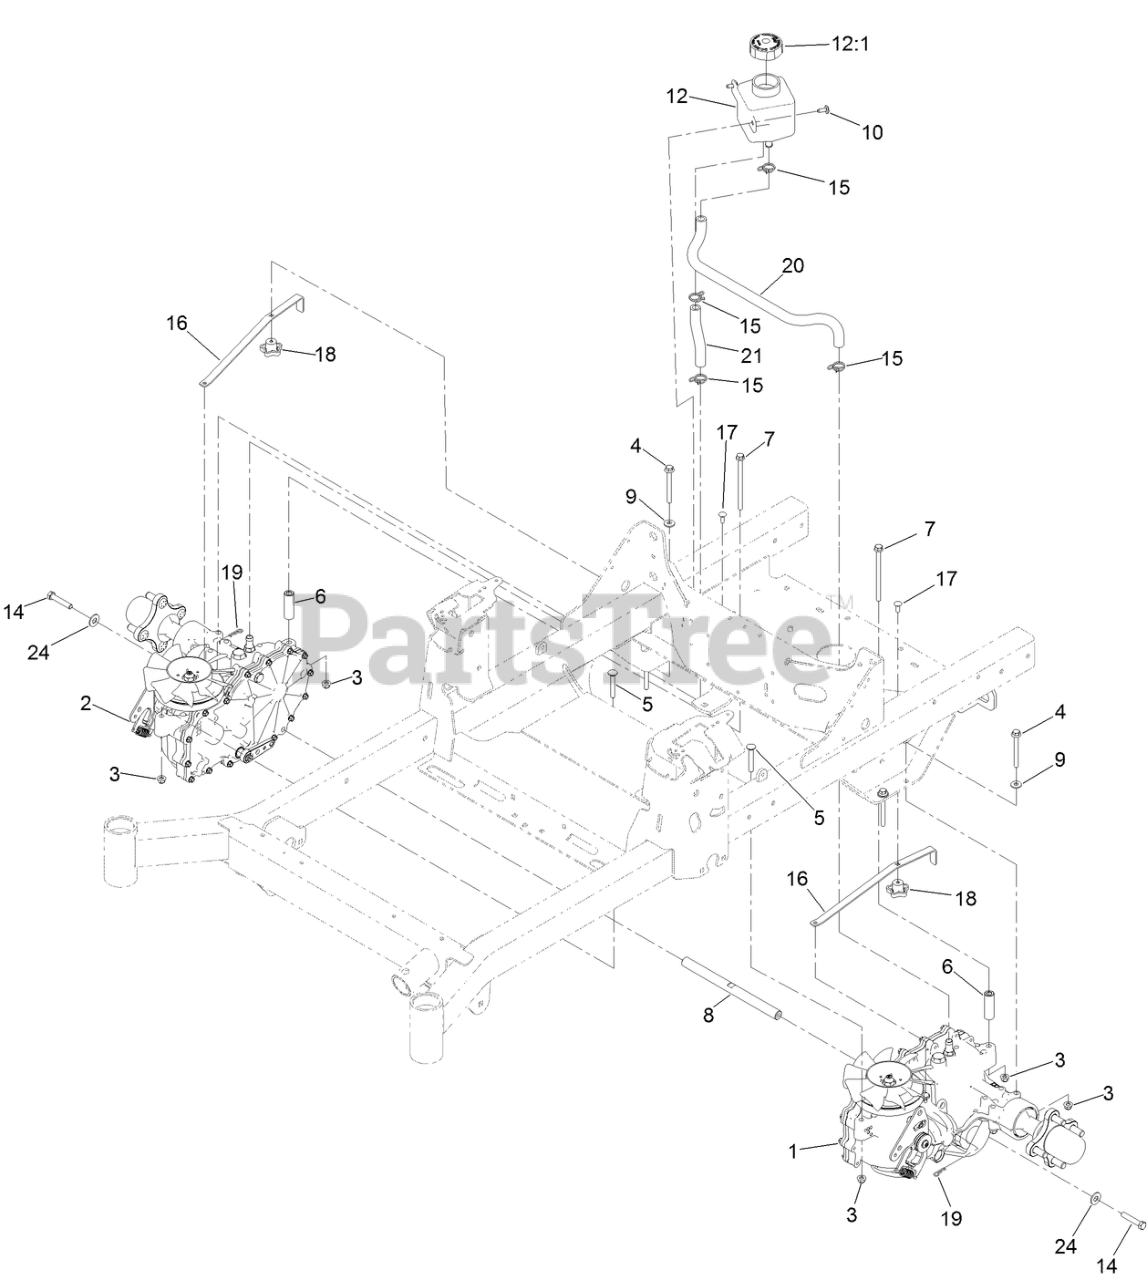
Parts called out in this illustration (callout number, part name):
1	LH TRANSAXLE ASM
2	RH TRANSAXLE ASM
3	NUT-HF, NI
4	SCREW-HHF
5	BOLT-CARR
6	SPACER-HYDRO
7	SCREW HHF
8	SHAFT-SPACER
9	WASHER-SPRING
10	SCREW-TORX
12	TANK-HYD
12:1	CAP-RESERVOIR, HYD
14	SCREW-HH W/LOCTITE
15	CLAMP-HOSE
16	ARM-BYPASS, HYDRO
17	BOLT-CARR
18	KNOB-HANDLE
19	PIN-COTTER
20	HOSE-HYDRAULIC
21	HOSE-HYDRAULIC
24	WASHER-FLAT
